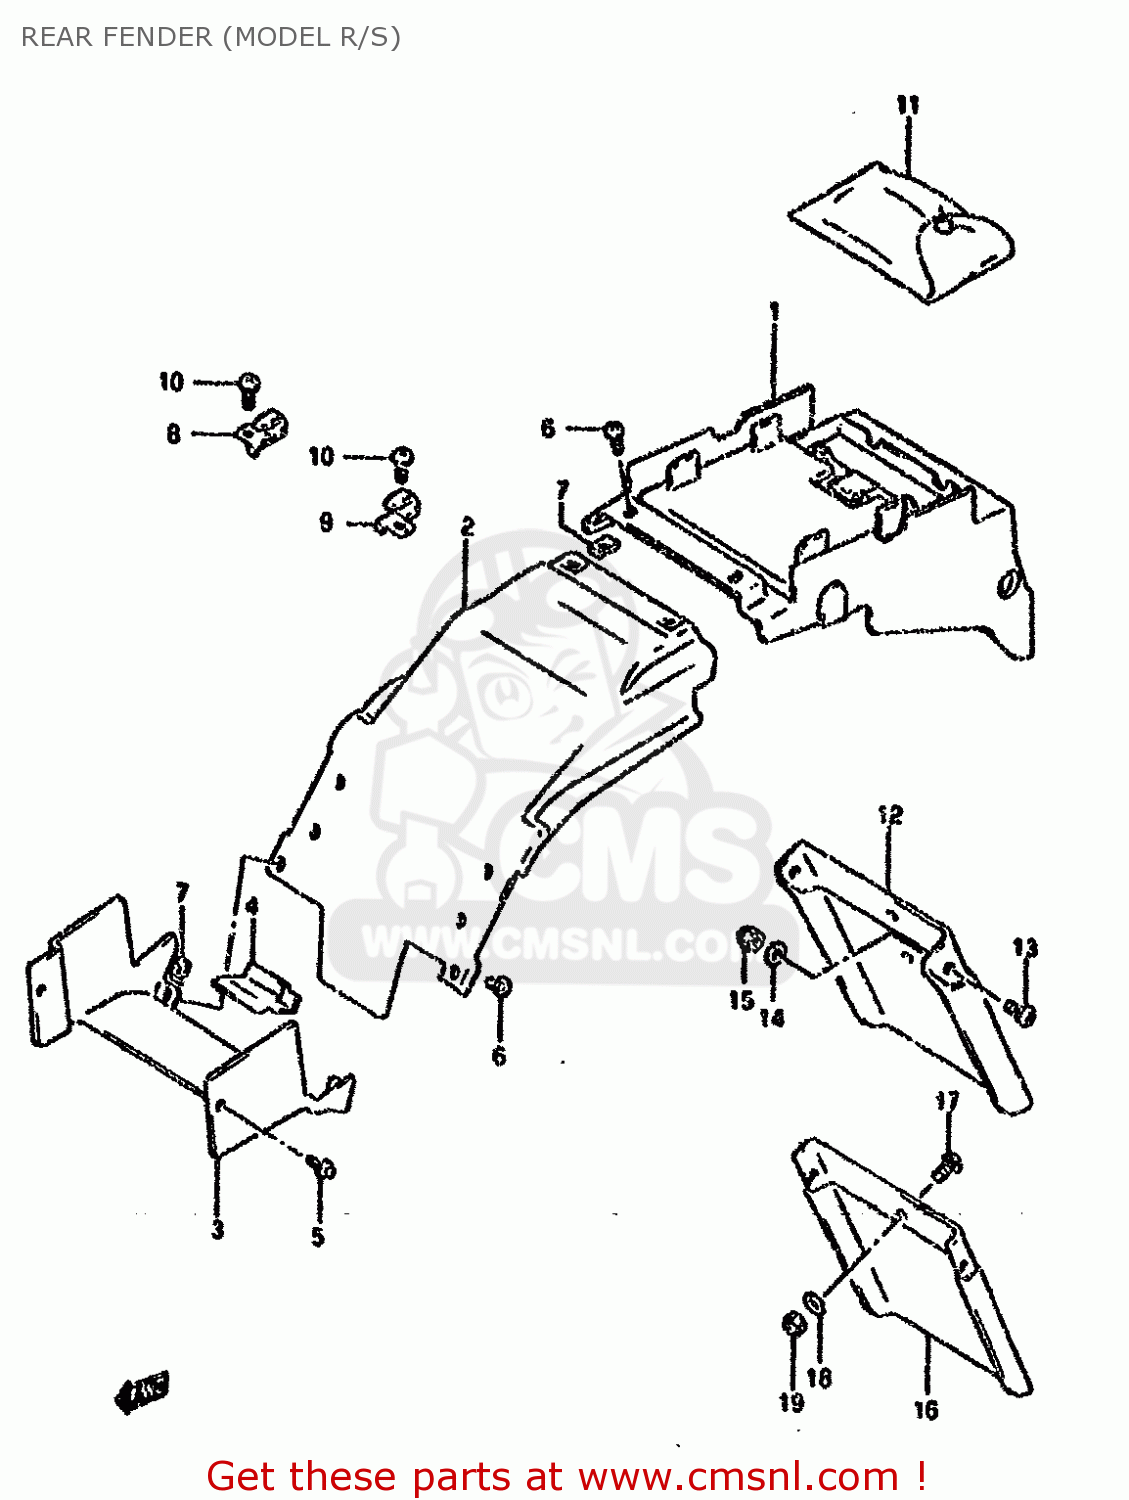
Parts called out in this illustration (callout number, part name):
1	FENDER,REAR UPPER
2	FENDER,REAR,UPPER,FRONT
3	FENDER,RR UPR FR NO.1
4	MUD GUARD,REAR FENDER
5	CLIP
6	SCREW 5X12
7	NUT,HEADLAMP HOUSING,UPPER
8	HOLDER,HELMET,R
9	HOLDER,HELMET,LEFT
10	SCREW 6X12
11	TOOL ASSY
12	EXTENSION,RR FENDER
13	SCREW
14	WASHER
15	NUT
16	MUD GUARD, REAR FENDER
17	SCREW
18	WASHER
19	NUT
20	HOLDER,HELMET,R
21	HOLDER,HELMET,LEFT
22	BOLT
23	TOOL ASSY
